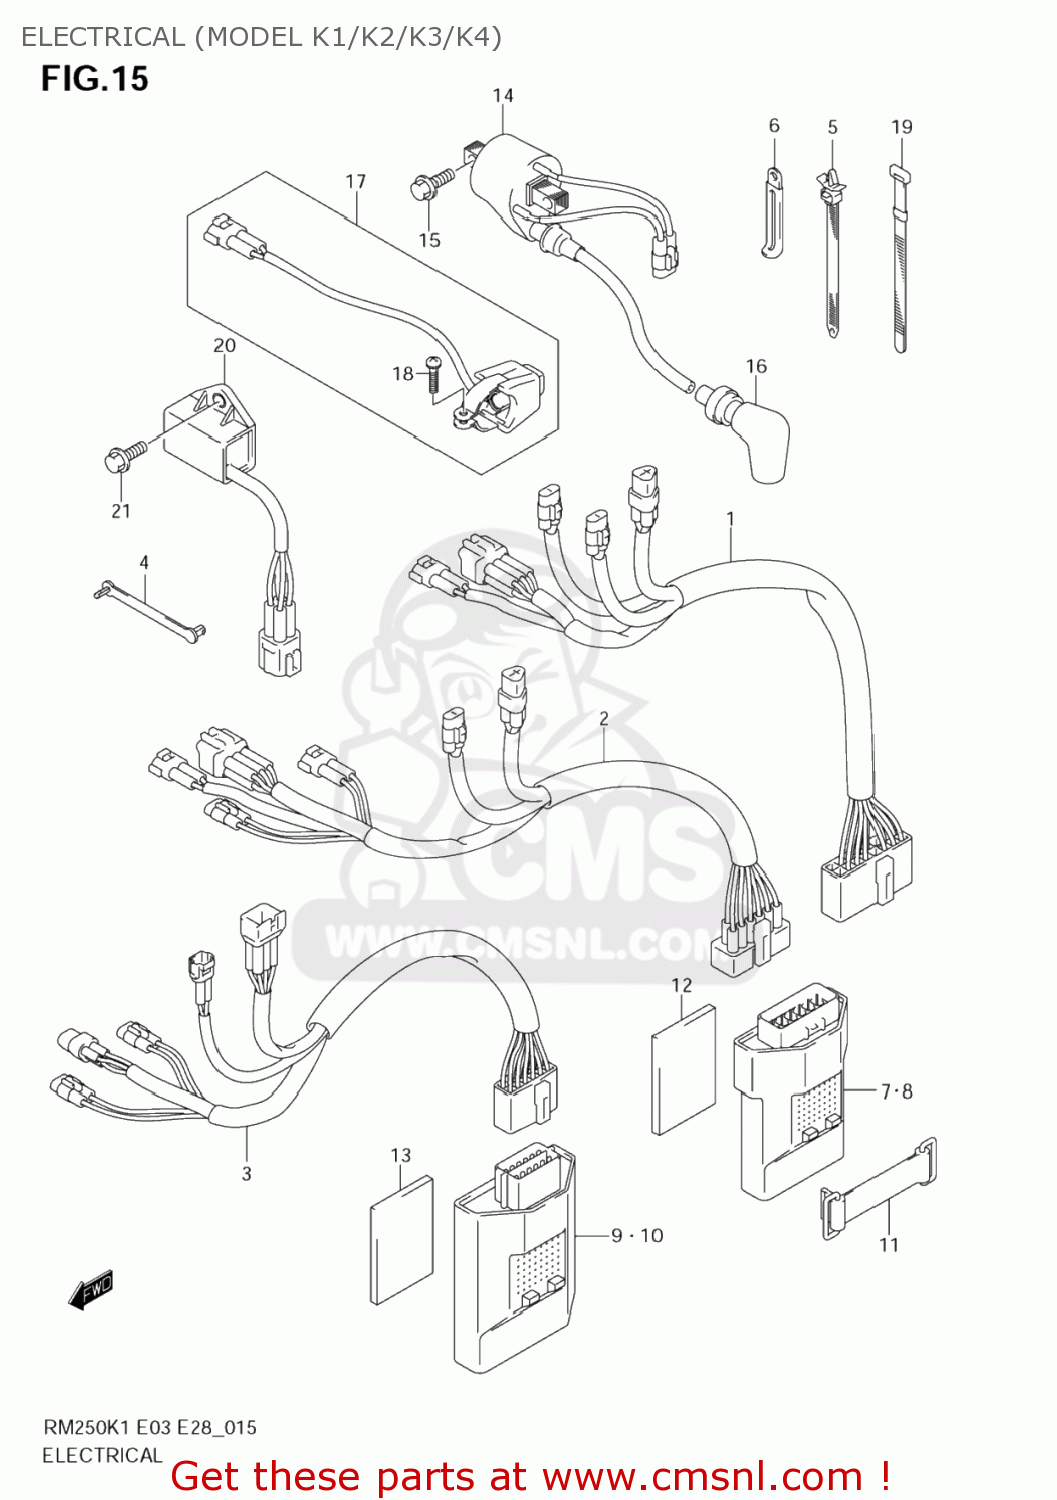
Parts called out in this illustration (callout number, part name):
1	HARNESS,WIRING
2	HARNESS,WIRING
3	HARNESS,WIRING
4	CLAMP(L:63)
5	CLAMP(L:90)
6	CLAMP(L:45)
7	CDI UNIT
8	CDI UNIT
9	CDI UNIT
10	CDI UNIT
11	BAND,CDI UNIT(L:80)
12	PROTECTOR(170X95X3.0)
13	PROTECTOR(170X95X3.0)
14	COIL ASSY,IGNITION
15	BOLT
16	CAP,SPARK PLUG
17	SWITCH ASSY,ENGINE STOP
18	SCREW
19	CLAMP(L:120)
20	RECTIFIER ASSY
21	BOLT
